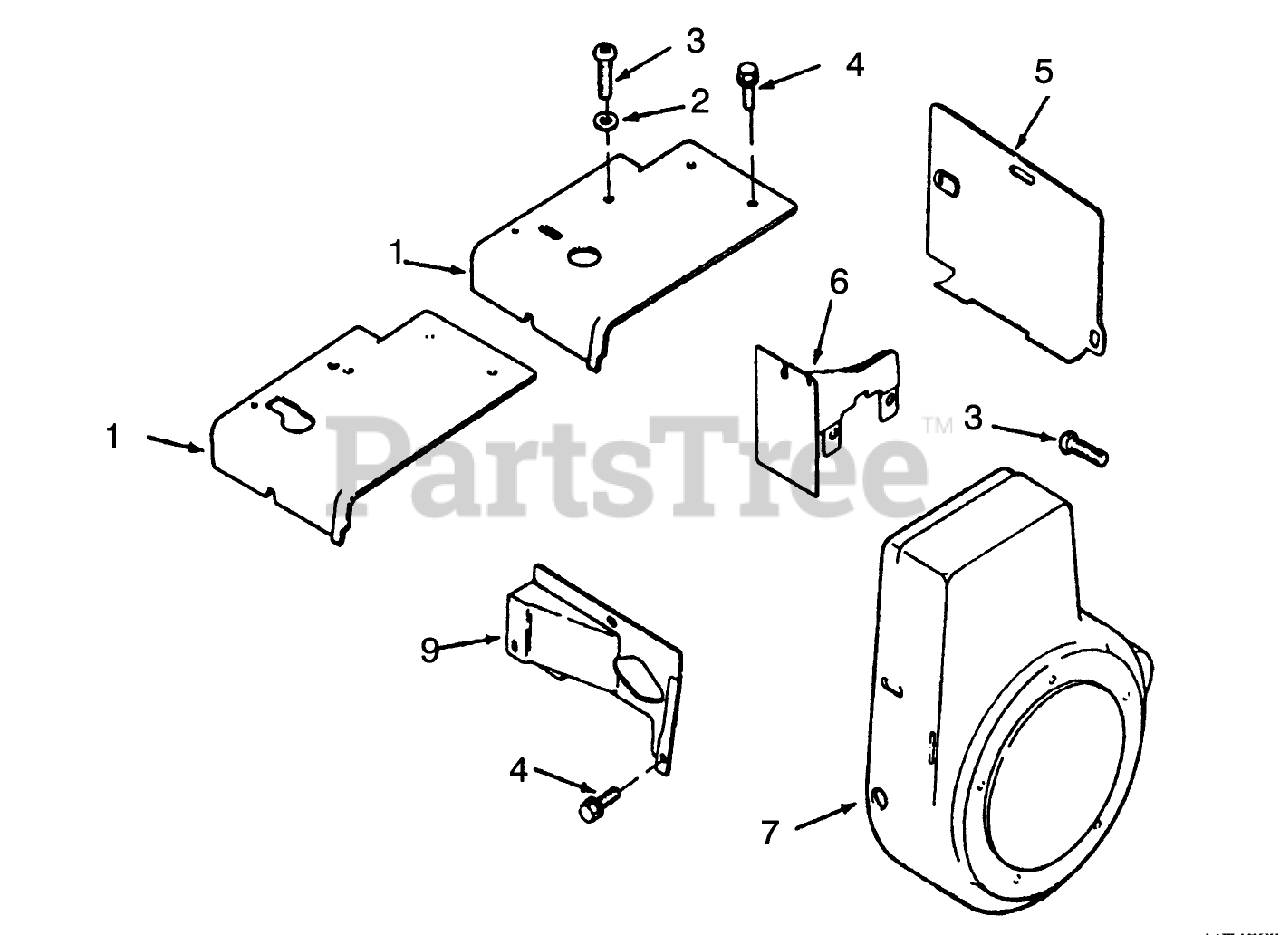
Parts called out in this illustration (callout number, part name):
1	KOHLER 45-063-08
2	KOHLER X-25-53
3	KOHLER 47-086-08
4	KOHLER 52-086-11
5	KOHLER 47-063-10
6	KOHLER 47-063-07
7	KOHLER 47-027-42
9	KOHLER 47-063-06
